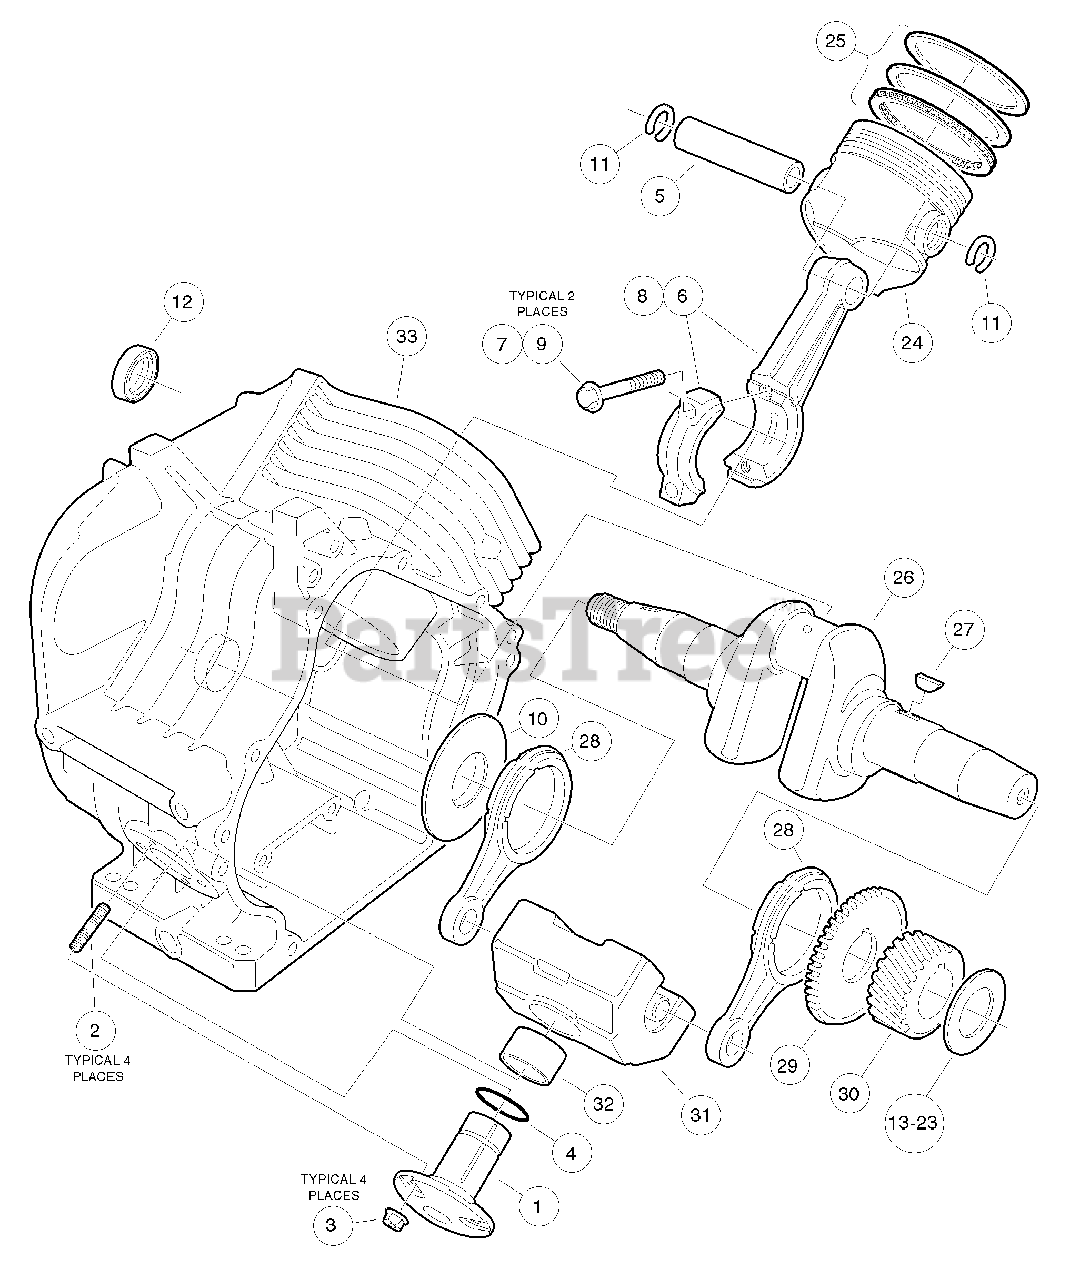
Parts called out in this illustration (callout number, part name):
1	Shaft, Guide, Counterbalance
2	Stud, 6x14
5	Pin, Piston
6	Asm, Con. Rod Std
8	Rod Assembly Connnecting Rod 0.5mm
13	Shim, Crankshaft, 1.18mm
14	Shim, Crankshaft, 1.25mm
15	Shim, Crankshaft, 1.32mm
16	Shim, Crankshaft, 1.39mm
17	Shim, Crankshaft, 1.46mm
18	Shim, Crankshaft, 1.53mm
19	Shim, Crankshaft, 1.60mm
20	Shim, Crankshaft, 1.67mm
21	Shim, Crankshaft, 1.74mm
22	Shim, Crankshaft, 1.11mm
23	Shim, Crankshaft, 1.81mm
24	Piston, FE400
25	Ring Set, Piston, FE400
26	Crankshaft, FE400
29	Spur Gear
30	Gear, Helical
31	Weight, Counterbalance, FE400
32	Bearing, Plain
33	Crankcase, FE400
